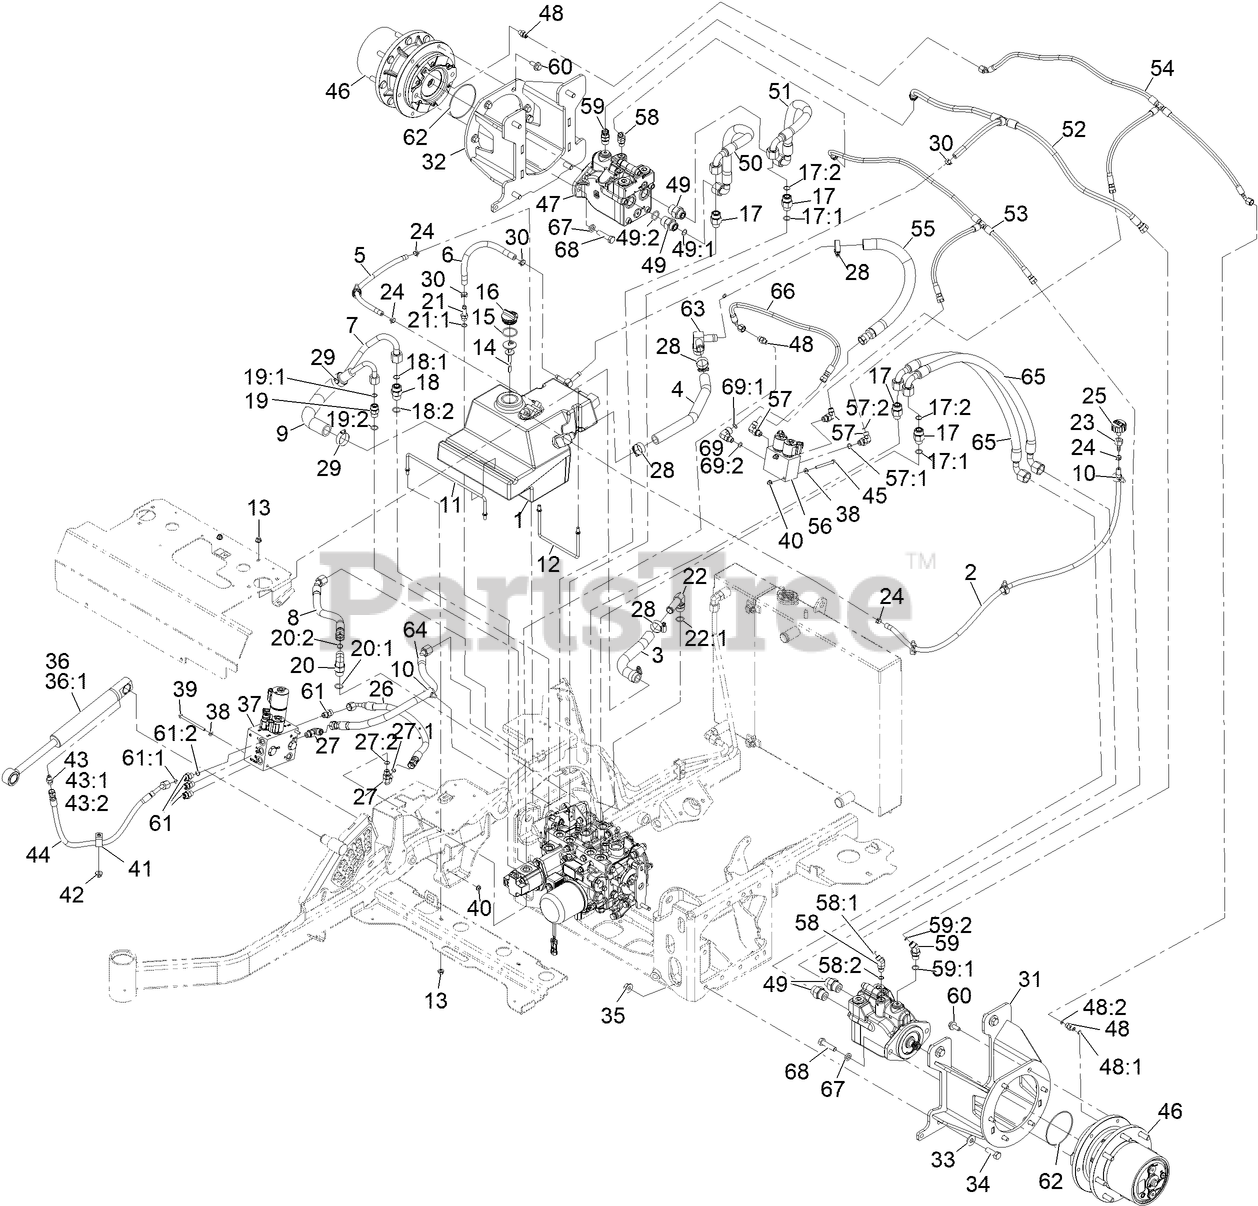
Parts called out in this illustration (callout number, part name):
1	HYD RESERVOIR ASM
3	HOSE-RETURN
4	HOSE-RETURN
7	TUBE ASM
8	HOSE ASM-HYD HP
9	HOSE-SUCTION
10	CLIP-TIE
11	ROD-SUPPORT, HYD TANK
12	ROD-SUPPORT, HYD TANK
13	NUT-HF, NI
14	DIPSTICK
15	O-RING
16	PLUG-PLASTIC
17	FITTING-STRAIGHT
17:1	O-RING
17:2	O-RING
18	FITTING-STRAIGHT
18:1	O-RING
18:2	O-RING
19	FITTING-STRAIGHT
19:1	O-RING
19:2	O-RING
20	FITTING-ELBOW, 90 DEG
20:1	O-RING
20:2	O-RING
21	ADAPTER-STRAIGHT
21:1	O-RING
22	FITTING-90
22:1	O-RING
23	FITTING-STRAIGHT
24	CLAMP-HOSE
25	BREATHER
26	HOSE ASM
27	FITTING-ELBOW, 90 DEG
27:1	O-RING
27:2	O-RING
28	CLAMP-HOSE
29	CLAMP-HOSE
30	CLAMP-HOSE
31	MOTOR MOUNT, L [BLACK]
32	MOTOR MOUNT, R [BLACK]
33	WASHER-SPRING
34	SCREW-HH
35	NUT-HHF
36	CYLINDER-LIFT
36:1	KIT, CYL REPAIR
37	VALVE ASM-LIFT AND FOLD
38	WASHER-FLAT
39	SCREW-HH
40	NUT-HF
41	CLIP-LOOM
42	NUT-HF, NI
43	FITTING-HYD, STRAIGHT
43:1	O-RING
43:2	O-RING
44	HOSE ASM
45	SCREW-HH
46	PLANETARY ASM-11.96:1
47	MOTOR-HYD, PISTON, 30CC
48	FITTING-STRAIGHT
48:1	O-RING
48:2	O-RING
49	FITTING-STRAIGHT
49:1	O-RING
49:2	O-RING
50	HOSE-HP
51	HOSE-HP
52	HOSE ASM-HYDLPTEE
53	HOSE ASM-HYD HP TEE
54	HOSE ASM-HYD HP TEE
55	HOSE ASM-HYDLP
56	VALVE-HYD, BRK-2SPD
57	FITTING-ELBOW, 90 DEG
57:1	O-RING
57:2	O-RING
58	FITTING
58:1	O-RING
58:2	O-RING
59	FITTING-HYD, 45 DEG
59:1	O-RING
59:2	O-RING
60	SCREW-HHF
61	FITTING-STRAIGHT
61:1	O-RING
61:2	O-RING
62	O-RING
64	HOSE ASM-HYD HP
65	HOSE-HP
66	HOSE ASM-HYD HP
68	SCREW-HH
69	FITTING-HYD, 90 DEG
69:1	O-RING
69:2	O-RING
